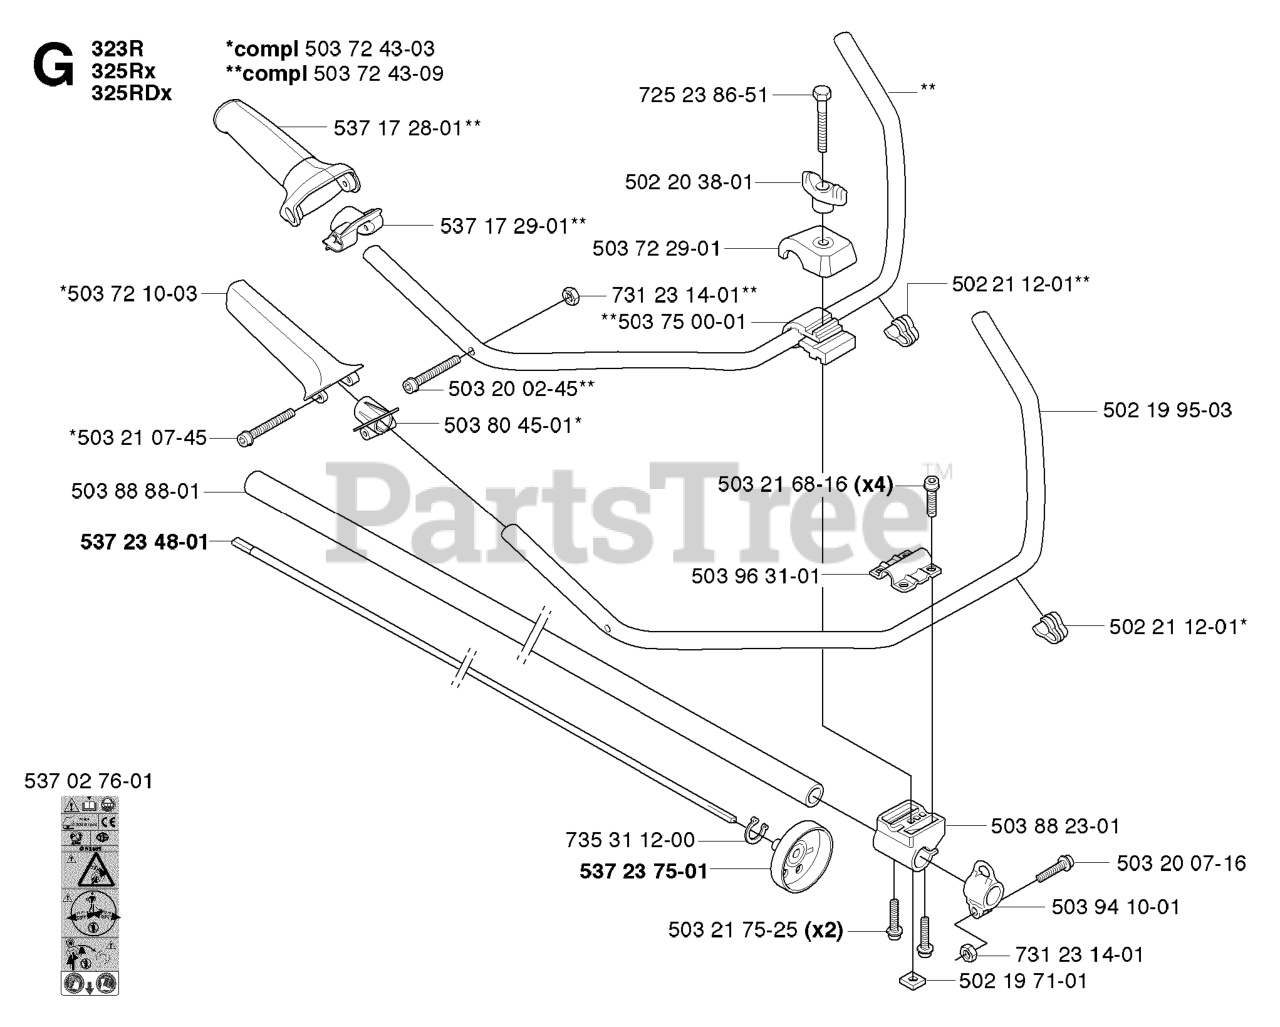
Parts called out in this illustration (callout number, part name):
1	MUFFLER TURBO
2	ENGINE SHEAVE
3	ELECTRIC CLUTCH
4	RESTRAINT KIT
5	JACKSHAFT MOUNT WELDMENT
6	HEAT SHIELD
7	MOUNTING BRACKET
8	AIR FILTER HOSE
9	ENGINE MOUNT-LT
10	ENGINE MOUNT-RT
11	ARM WELDMENT
14	NUT M8-1.25 STOVER
15	SPINDLE WASHER
18	BELT, PRIMARY BZ
19	ENGINE, BELT MULE
20	AIR FILTER ASSY
21	CLAMP, AIR HOSE
22	WASHER, HEAVY
23	BUSH 1-1/8 X 10 GA ZD
24	GREASE ZERK LONG
25	WASHER 3/8 SAE FLAT
26	WASHER 1/2 FLAT
27	HCS 5/16C X 3/4
28	BOLT 7/16F X 2 1/2
29	HCS 1/2C X 2 3/4
30	HTB M8-1.125 X 25MM
31	HCS 1/2C X 1 1/4 SERRATED HEAD
32	HEX SCREW 1/2-13 X 2.5" GR 5
33	HCS 5/16C X 1
35	HCS 3/8-16 X 3-1/2 GR5 ZD
36	NUT 5/16 NYLOC
37	NUT 3/8-16 NYLOC
38	NUT 1/2-13 HEX NYLOC ZD
39	WASHER 7/16 LOCK
40	WASHER.LOCK.HVY.HLCL.SPR.5/16
41	KEY 1/4 SQ X 2-1/2
42	WASHER 5/16 FLAT
43	HCS 7/16F X 1 1/2
44	COMBO SPACER
45	HOUSING, DIE CAST
46	BEARING
48	SPINDLE WASHER
51	KEY 1/4 SQ X 1 1/8
52	BUSHING.MACHINE.18.GAUGE
55	AIR FILTER
56	SAFETY ELEMENT
57	BODY, STRAIGHT
58	PRECLEANER ASM
59	MOUNTING BRACKET
63	NUT 5/16C WHIZ
64	HCS 5/16C X 1 1/4
539106327	STUB SHAFT
539109177	MANIFOLD GASKET
